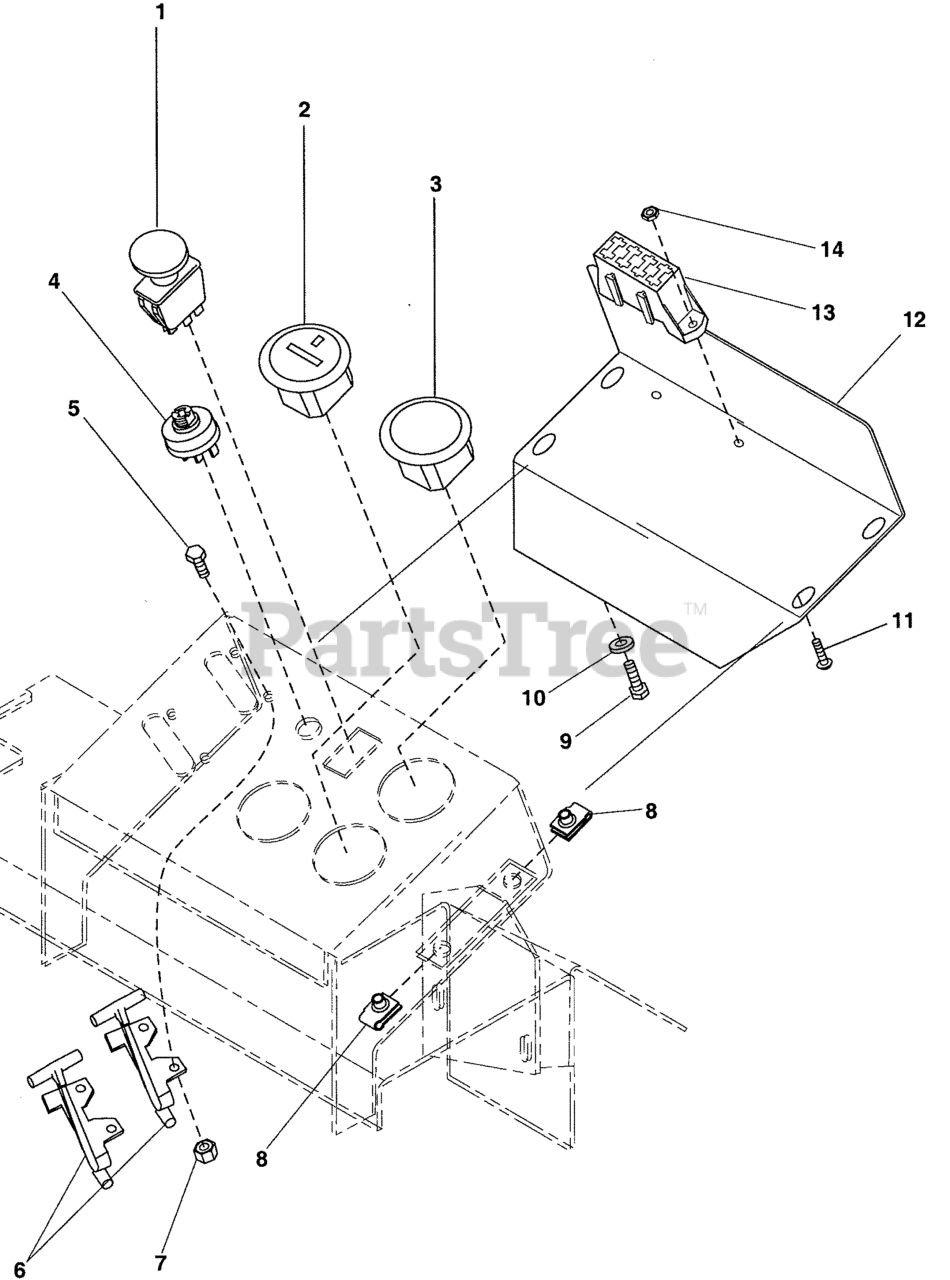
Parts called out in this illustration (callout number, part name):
1	SWITCH, BLADE ENGAGEMENT
2	HOUR METER
3	VOLTMETER
4	SWITCH, IGNITION, 6 POST
5	BOLT, 5/16-18 X 3/4 GD5
6	CABLE, Throttle & Choke
7	NUT, 5/16-18 HEX SERRATED FLANGE (SMALL)
8	BODY CLIP, 5/16-18-7GA MATERIAL
9	BOLT, 5/16-18 X 1 GD5 YZ
10	WASHER, 5/16" SAE
11	SCREW, #10-24 X 1 RS, CZ
12	COVER, CONTROL PANEL
13	FUSE BLOCK
14	NUT, Hex, Nylon Lock, #10-24
